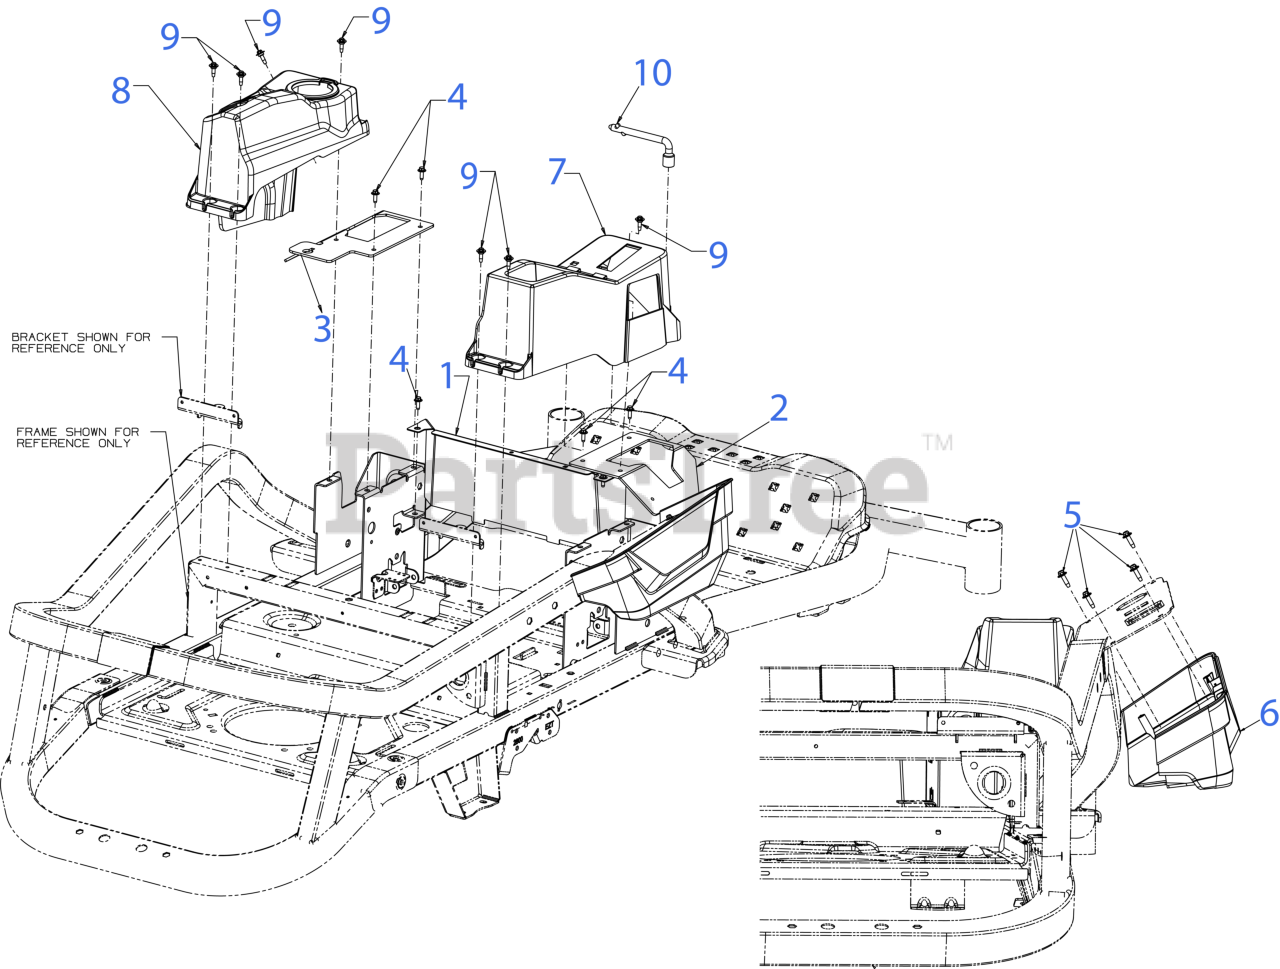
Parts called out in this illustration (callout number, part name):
1	SEAT BOX FRONT PLATE
2	CONTROL BRACKET (RH)
3	CONTROL BRACKET (LH)
4	SCREW M6-1 x .625
5	SCREW 1/4-10 x .750
6	CONTROL PANEL CONSOLE
7	CONSOLE (RH)
8	CONSOLE (LH)
9	SHOULDER SCREW M6-1 .368 X.115
10	MULTI TOOL 1/2" SOCKET
